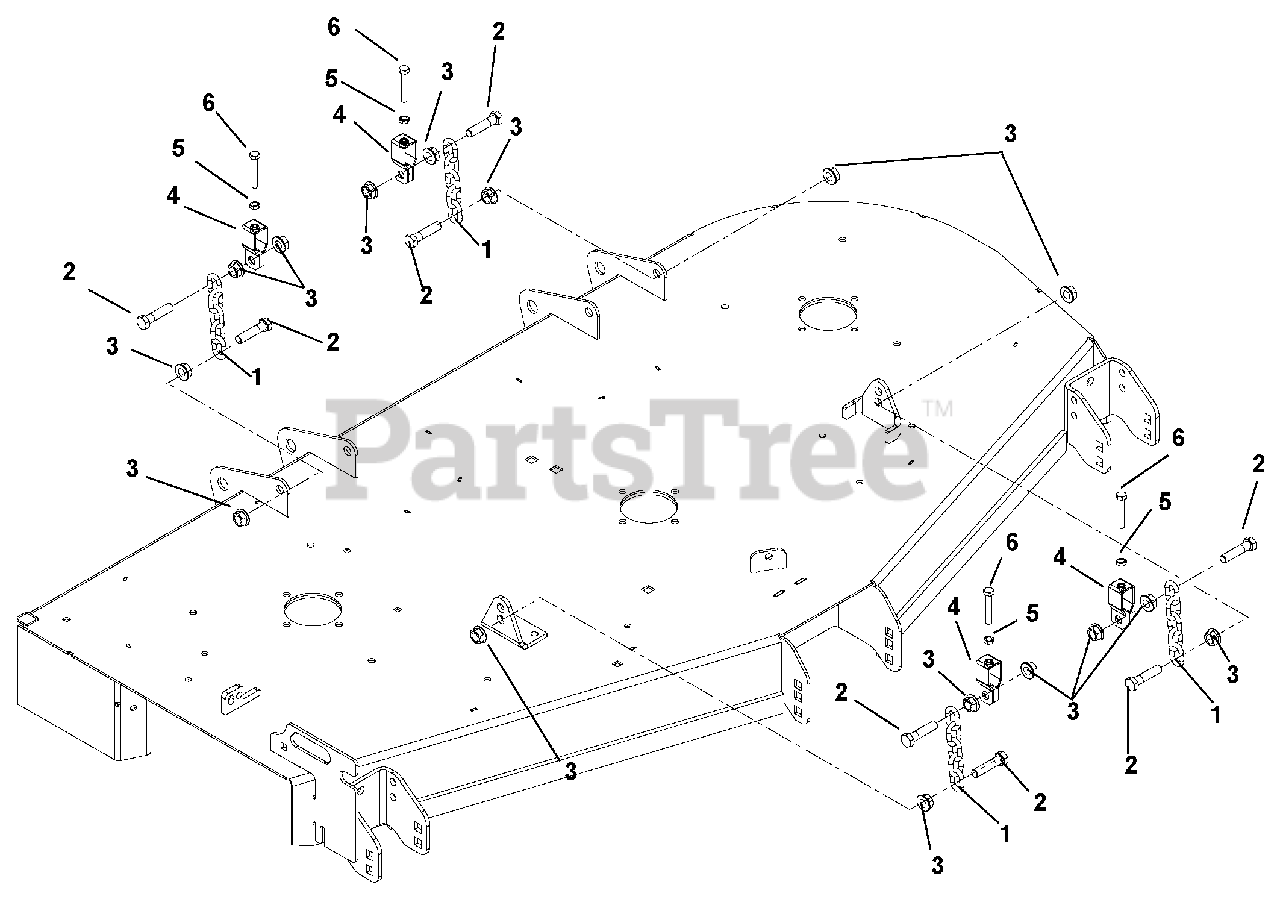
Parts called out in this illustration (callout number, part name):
1	Chain, Link
2	Bolt, Hex M12-1.75 x 50 Class 8.8
3	Nut, Spin Lock Flange M12-1.75
4	Bracket, Deck Leveling
5	Nut, Jam .312-18
6	Bolt, Hex .312-18 x 2.00 FTH Grade 5
